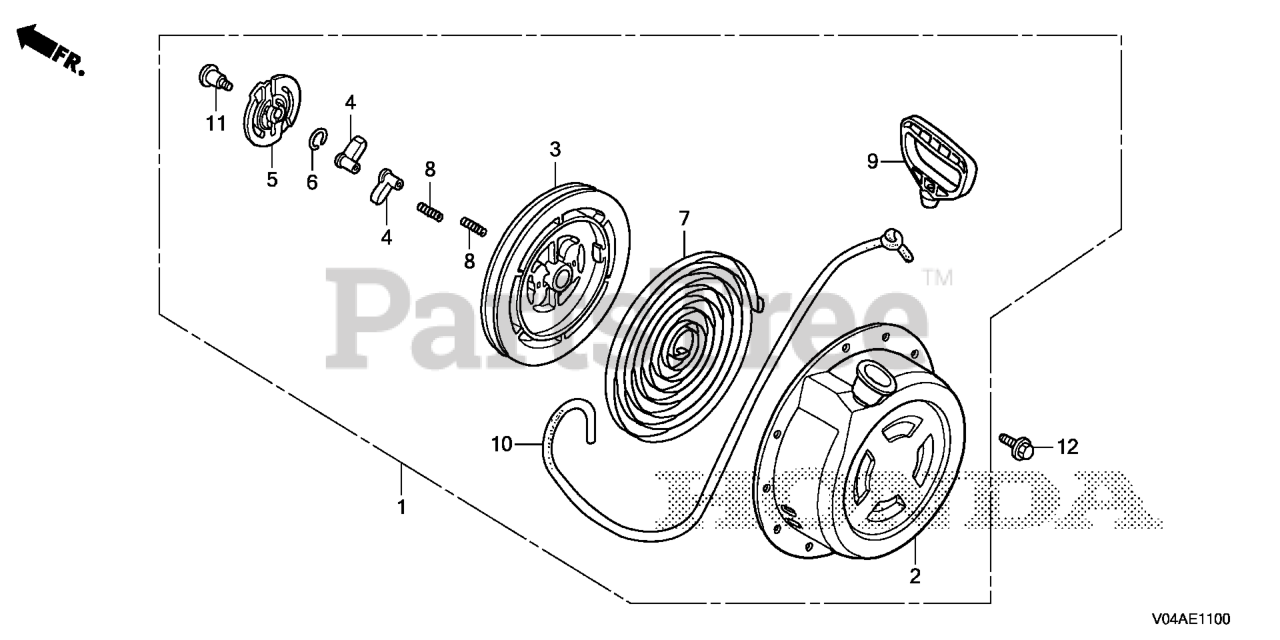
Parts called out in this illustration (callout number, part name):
1	STARTER ASSY., RECOIL *R280* (POWER RED)
2	CASE, RECOIL STARTER *R280* (POWER RED)
3	REEL, RECOIL STARTER
4	RATCHET, STARTER
5	GUIDE, RATCHET
6	SPRING, FRICTION (ENGINE NO.)
7	SPRING, RECOIL STARTER
8	SPRING, RETURN (ENGINE NO.)
9	GRIP, STARTER
10	ROPE, RECOIL STARTER (#5X55") (NA USE ALT:08550-ZG921-11)
11	SCREW, SETTING (ENGINE NO.)
12	BOLT, FLANGE (6X8)
